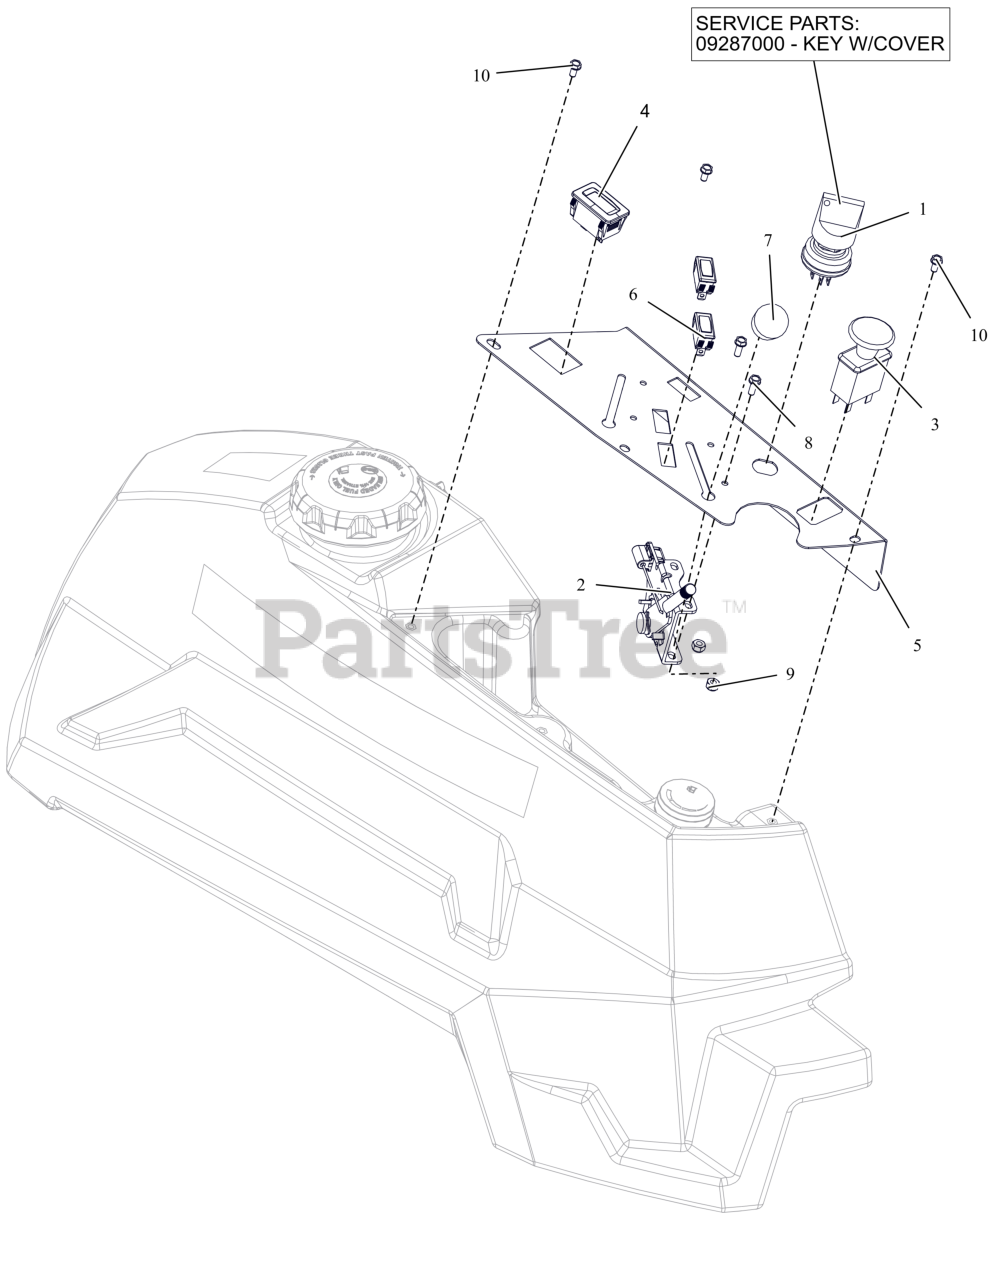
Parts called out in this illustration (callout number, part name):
1	SWITCH, IGNITION
1	KEY, W/ SHIELD
2	CABLE, PRO-CTRL 43.00"
3	SWITCH, CLUTCH
4	HOUR METER
5	PT400 CONTROL PANEL - RED
6	LIGHT, INDICATOR (RED)
7	KNOB-CONTROL-BLACK .38-16X.50
8	BLT, HWH #10-24X.50 ZCC
9	NUT-LK-NYL #10-24 G2 ZCC
10	SCR-MCH 10-24X.38 HWHSTAINLESS
